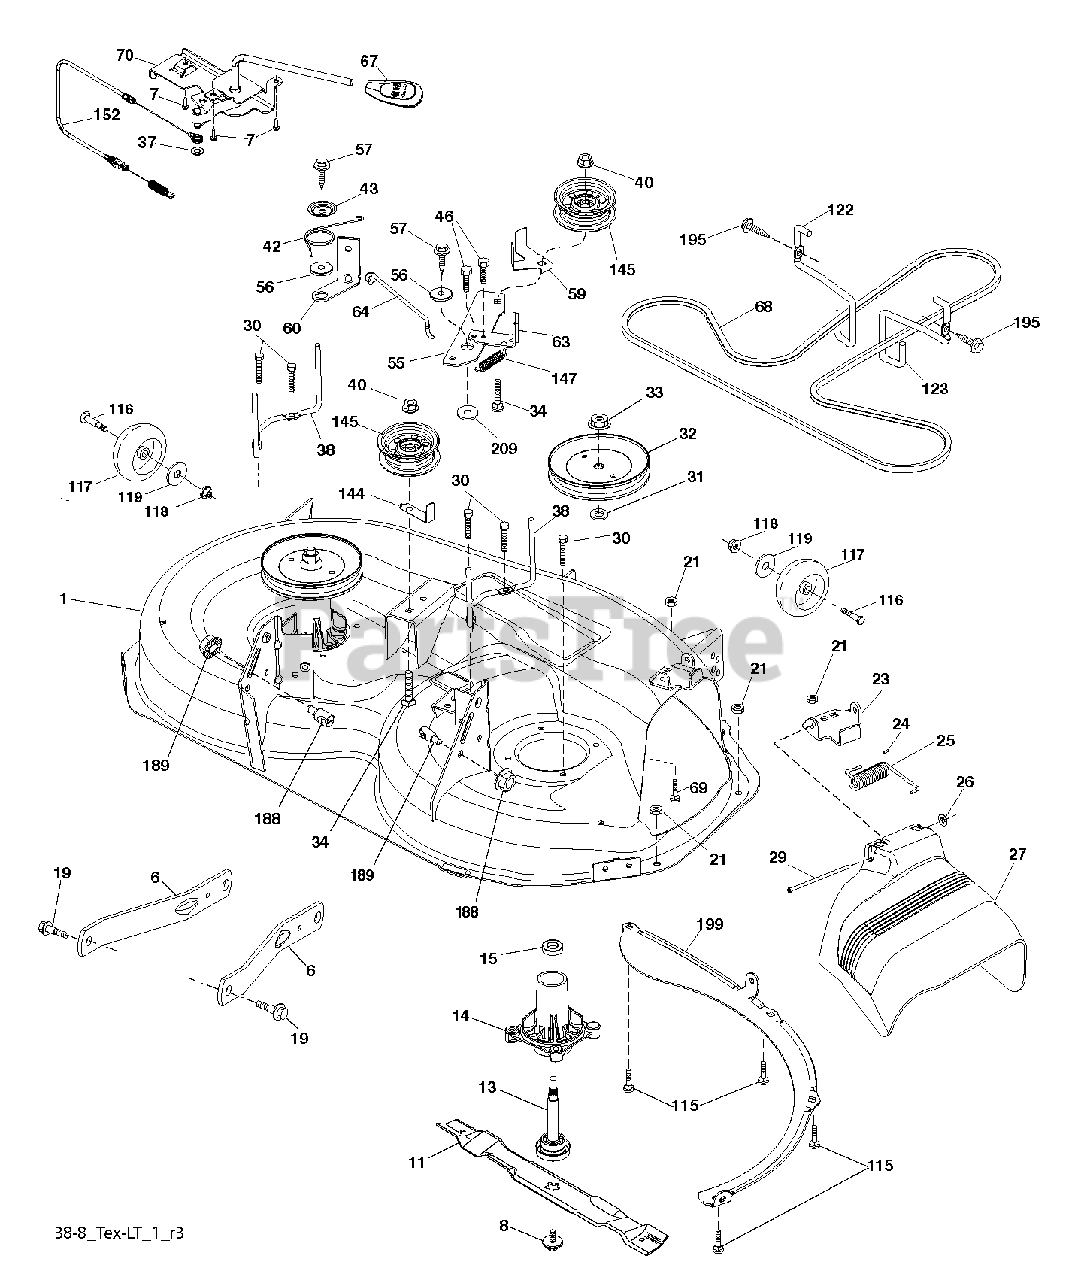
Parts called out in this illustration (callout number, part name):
1	MOWER HOUSING
6	ARM.SUSPENSION.MOWER.R
7	SCREW.#10 X 0.750.BOS
8	BOLT.WASHER.ASM.7/16-2
11	BLADE 38" PREMIUM
11	BLADE.HI.LIFT.38"
13	SHAFT.ASM.MDRL.N/GREASE.38
14	HOUSING.MANDREL.4PT.
19	BOLT.SHOULDER
21	LOCKNUT
23	BRKT.DEFLECTOR.38"2005+
24	CAP-SLEEVE LT
25	SPRING.TORSION.DEFLECT
26	NUT PUSH M
27	SHIELD, DEFLECTOR
29	ROD.HINGE
30	SCREW, WASHER HEAD
31	WASHER.SPACER.MANDREL
32	PULLEY.MANDREL.5.0.PD.38"
33	NUT.FLANGE.LOCK.TOP
34	BOLT.3/8-16X1.50
37	WASHER
38	KEEPER BELT LH MANDREL
40	NUT LOCK FLG 3/8-16 UNC
42	SPRING.TORSION.BRAKE
43	SRPING.TORSION.RETAINE
46	SCREW.1/4-20X5/8
56	SPACER.RETAINER
57	SCREW 3/8-16X1
59	GUARD, BELT
60	ARM BRAKE MOWER RH 38"
63	RP ARM.BRAKE.MOWER.38"LH.TEX
64	LINK BRAKE
67	HANDLE.CLUTCH.CABLE.LT
69	BOLT
70	CLUTCH.ASM.MANUAL.LT.PRED
115	BOLT
116	BOLT M
117	WHEEL.GAGE.HALF.SPOKED
118	LOCKNUT
119	WASHER
122	KEEPER BELT ENGINE LH
123	KEEPER BELT RH
144	KEEPER BELT
145	PULLEY.IDLER.48"PRIMARY
147	SPRING RETURN
152	CLUTCH CABLE
188	STUD.FASTNER.W/ANTI-ROTATE
189	NUT LOCK HEX FLANGE 5/16-18
195	SCREW, 3/8-16X3/4
199	BAFFLE.VORTEX.FRONT.38"
209	WASHER 12/32X2X10GA
